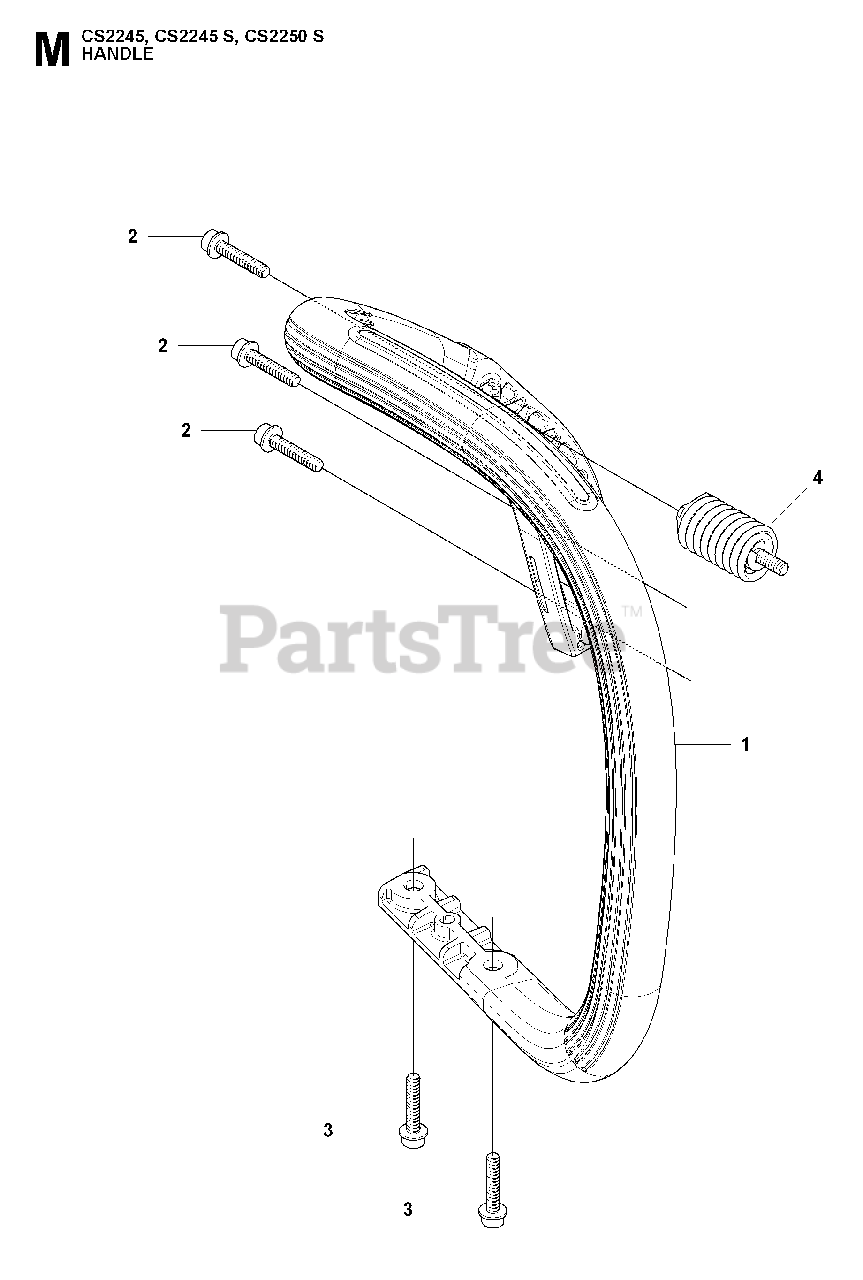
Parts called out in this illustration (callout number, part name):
1	FRONT HANDLE
2	SCREW IHSCFT
4	INSULATOR
